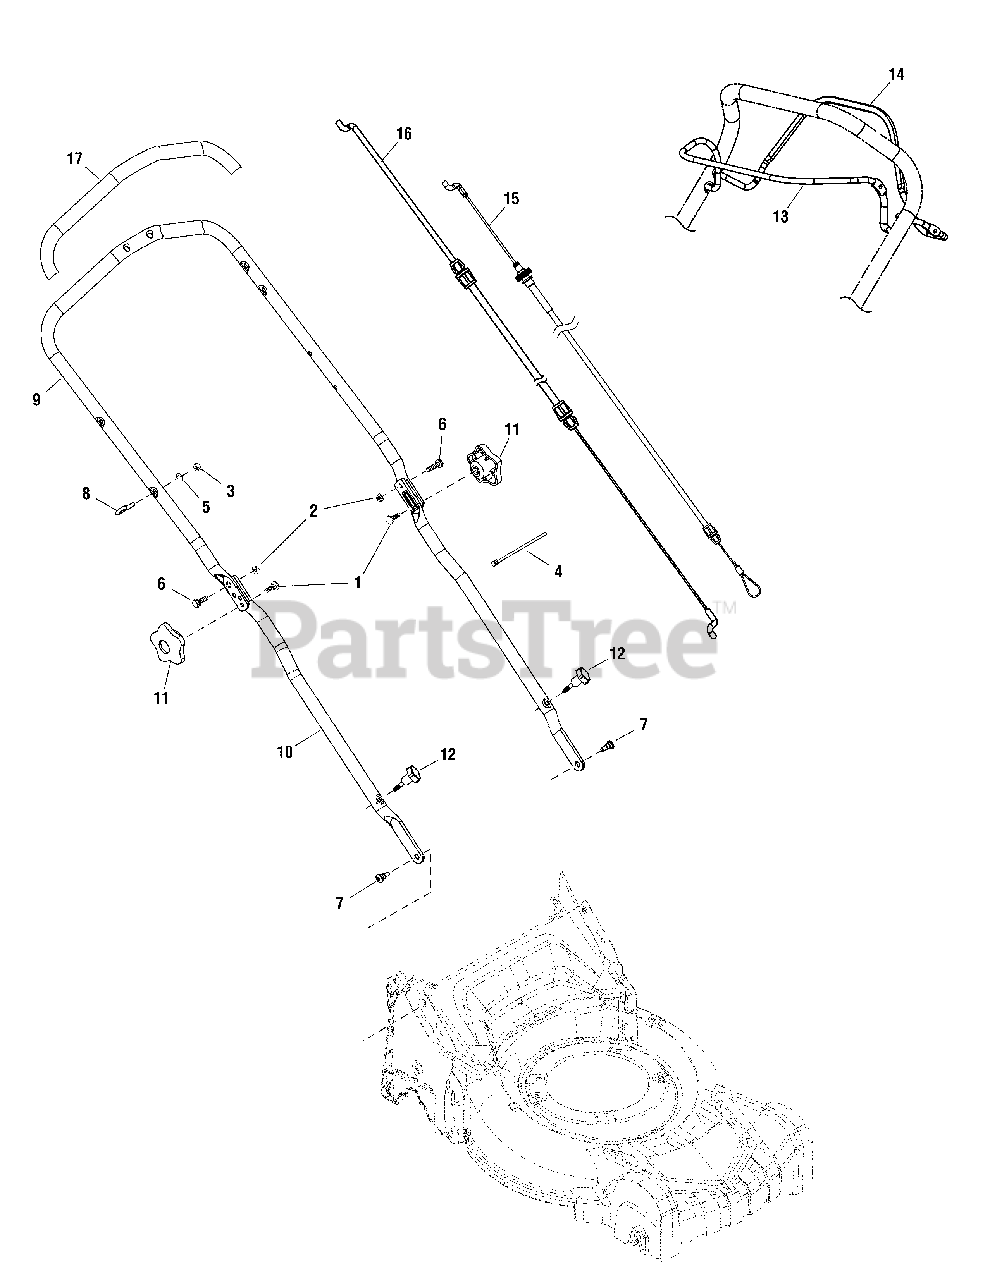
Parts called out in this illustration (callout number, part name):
1	BOLT, 5/16-18 x 1 G5
2	NUT, Nylock Flanged, 1/4-20
3	NUT, Nylock, M6
4	CABLE CLIP
5	WASHER, A6.4
6	SCREW, 1/4-20
7	BOLT, Shoulder
8	BOLT, Eye
9	HANDLE, Upper
10	HANDLE, Lower
11	WING KNOB, 5/16-18
12	WING KNOB
13	BAIL, Control
14	BAIL, Drive
15	CABLE, Drive
16	CABLE, Control
